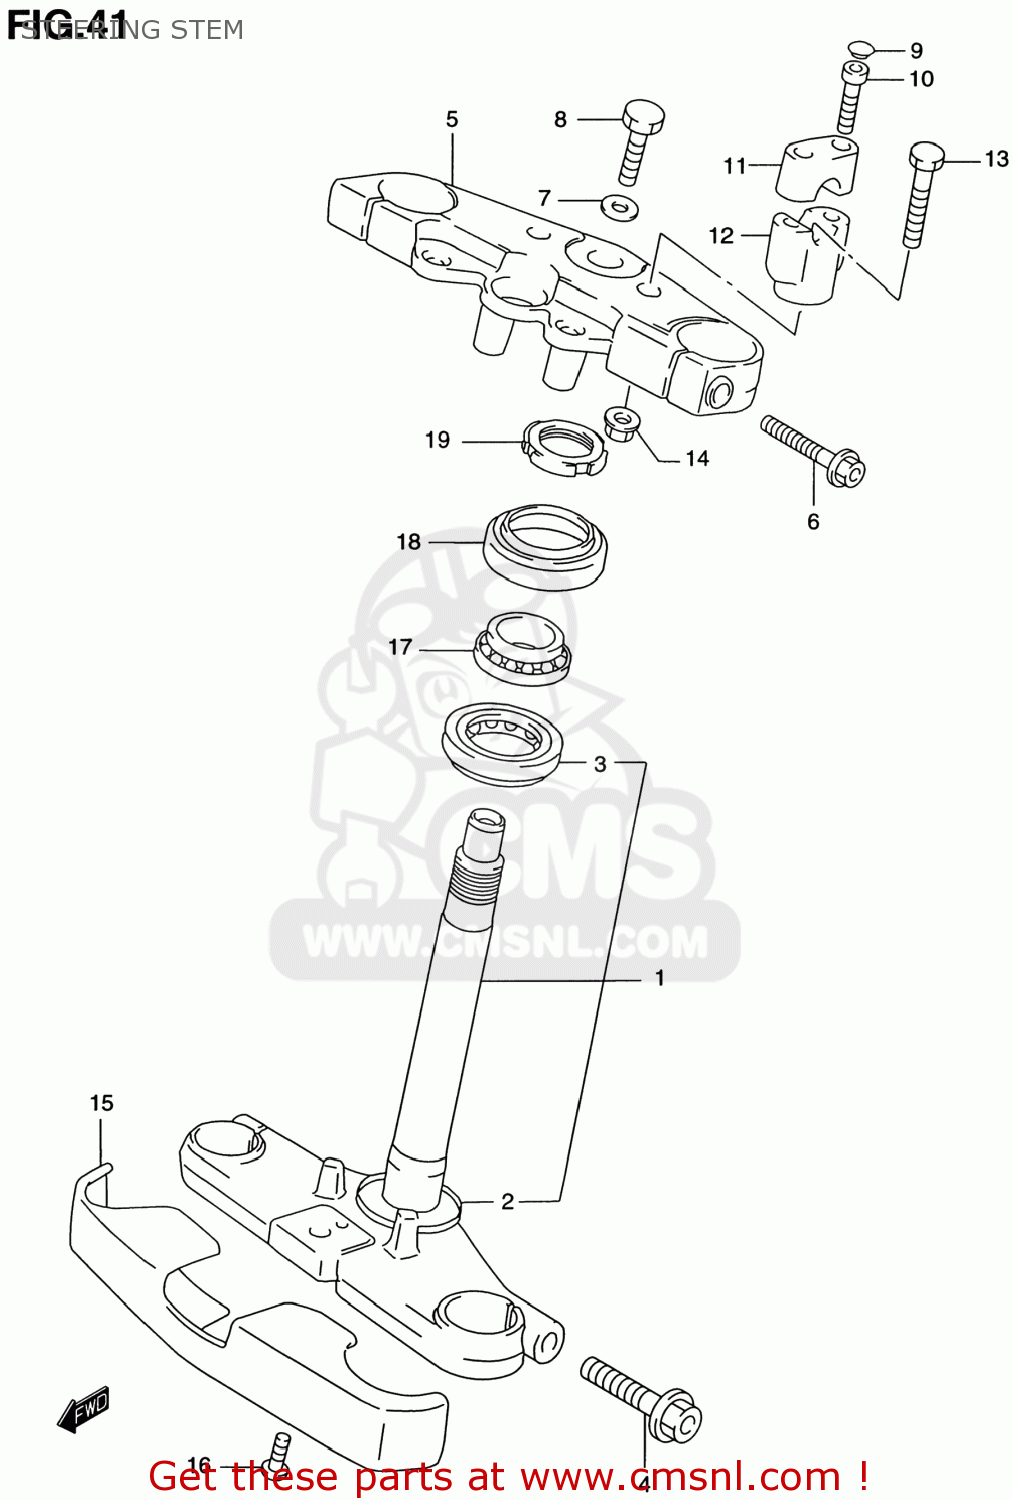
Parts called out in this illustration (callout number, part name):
1	STEM,STEERING
2	SEAL,STEERING LWR
3	BEARING(30X55X17)
4	BOLT
5	HEAD,STEERING STEM
6	BOLT
7	WASHER,STEERING STEM
8	BOLT,STEERING STEM HEAD
9	CAP(OD:11)
10	BOLT
11	HOLDER,HANDLE UPR
12	HOLDER,HANDLE UNDER
13	BOLT
14	NUT
15	COVER,FR FORK UNDER
16	SCREW(6X16)
17	BEARING(25X47X15)
18	DUST SEAL,STEERING UPR
19	NUT,STEERING STEM(25X44X10)
